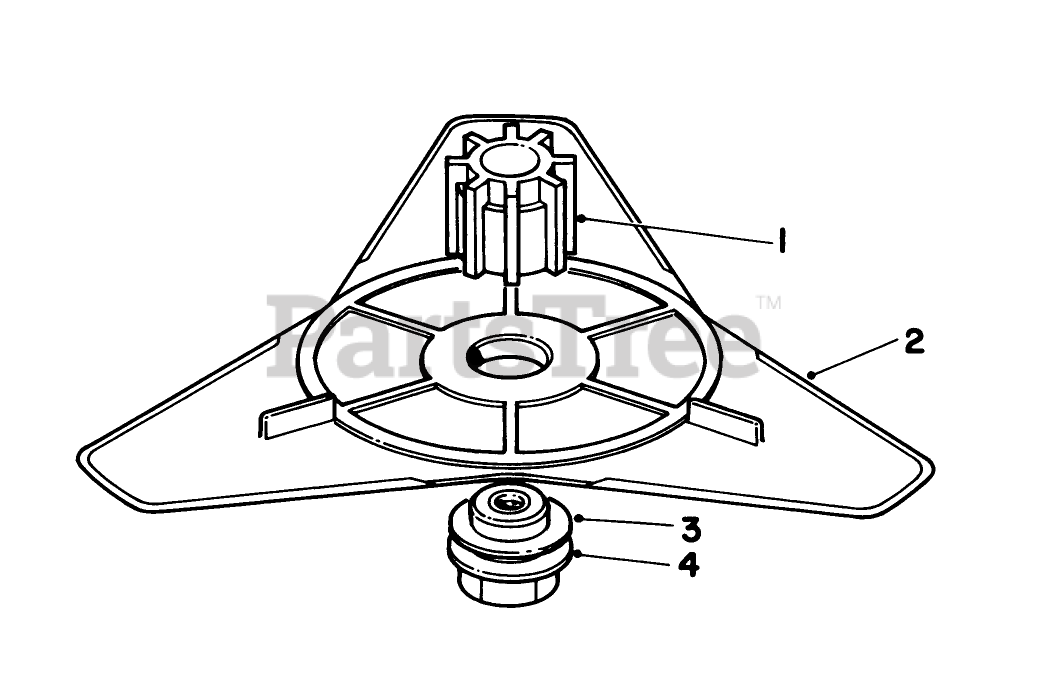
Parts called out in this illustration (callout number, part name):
1	BLADE ADAPTER
2	FLEX BLADE PKG
3	FLAT WASHER
4	ADAPTER NUT
